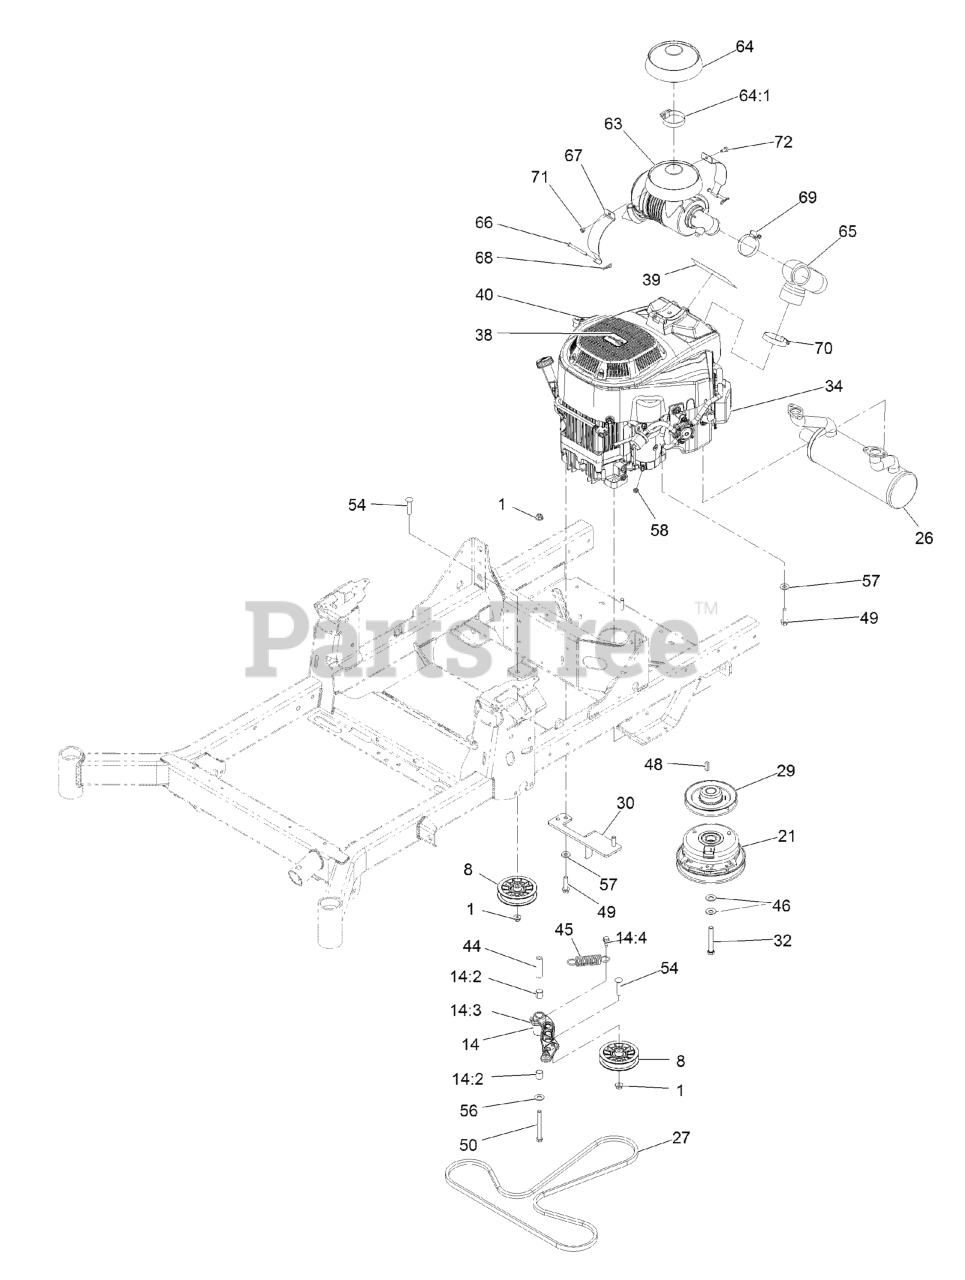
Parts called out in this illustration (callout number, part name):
1	NUT-HF, NI
8	PULLEY-FLAT IDLER
14	IDLER ARM ASM
14:2	SLEEVE-BEARING
14:3	FITTING-GREASE, 90 DEG
14:4	SCREW-THD ROLL, HWH
21	CLUTCH 1.00
26	MUFFLER
27	BELT-V
29	SHEAVE-ENGINE
30	ANCHOR-CLUTCH
32	SCREW-HH W/LOCTITE
34	ENGINE-2P77F-HD
39	DECAL-ENGINE 708 V-TWIN E
40	DECAL-DRAIN, OIL
44	BUSHING-PIVOT, IDLER
45	SPRING-EXTENSION
46	WASHER-SPRING
49	SCREW-HWH
50	SCREW-HH
54	SCREW-CARR
56	WASHER-FLAT
57	WASHER-BELLEVILLE
63	AIR CLEANER ASM
64	RAIN CAP KIT
64:1	CLAMP-HOSE
65	HOSE-INTAKE
66	PIN-CLEVIS
67	STRAP-CANISTER, AIR
68	PIN-COTTER
69	CLAMP-HOSE
70	CLAMP-HOSE
71	NUT-HEX
72	SCREW-HH
